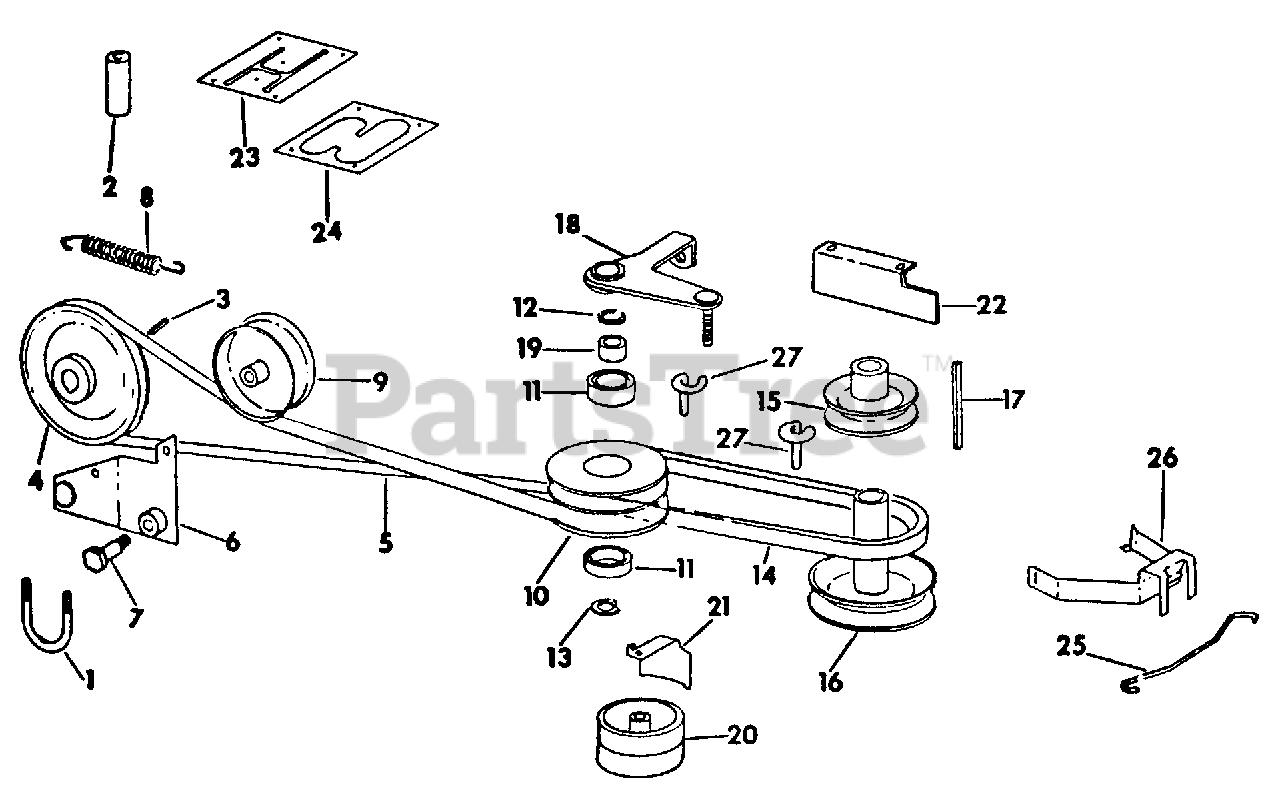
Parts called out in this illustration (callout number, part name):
2	Spacer, Transaxle Mounting
3	Key, 3/16 X 3/4 Woodruff No. 9
4	Pulley, Transaxle
5	Belt, Mower & Final Drive
6	Arm Assy, Belt Tensioning
7	Bolt, IPTO Shoulder
8	Spring, Extension
9	Pulley, Final Drive Idler
10	Pulley, Intermediate Drive
11	Bearing, Intermediate Pulley
12	Ring, External Retaining
13	Ring, Internal Retaining
14	Belt, Clutching
15	Pulley, Engine Drive
16	Pulley, Mower Drive, 5-1/4 inch diameter
17	Key, 1/4 X 2-3/4 Sq Parallel
18	Bushing Assy, Clutch
19	Bushing
20	Pulley, Mower Shifter Idler
21	Guide, Belt
22	Guide, Belt
23	Cover, Gear Shift Hole
24	Plate, Gear Shift Hole
25	Support, Belt Guide
26	Guide, Engine Belt
27	Guide, Transaxle Belt
